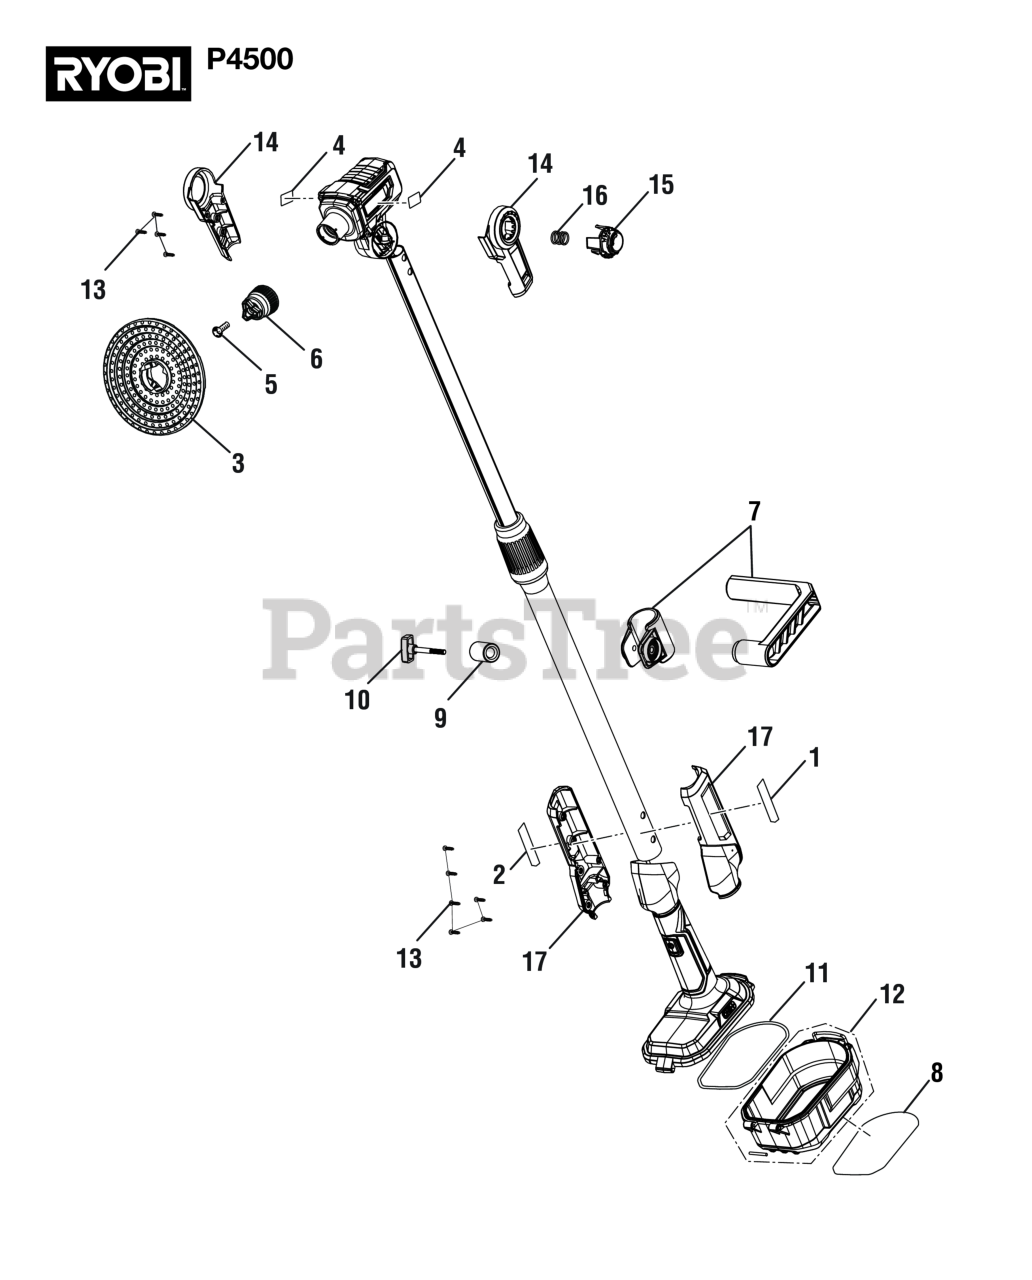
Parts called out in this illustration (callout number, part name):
1	Logo Label (Handle-Left)
2	Logo Label (Handle-Right)
4	Logo Label
5	Screw (M4 x 14 mm, T20 Torx Pan Hd.)
6	Brush Adaptor
7	Handle and Clamp Assembly
8	Data/Warning Label
10	Knob w/Pin
12	Battery Compartment Assembly
13	Screw (M3.5 x 14 mm, T15 Torx Pan Hd.)
14	Pivot Housing Assembly
15	Pivot Button
16	Pivot Button Spring
17	Handle Coupler Assembly
